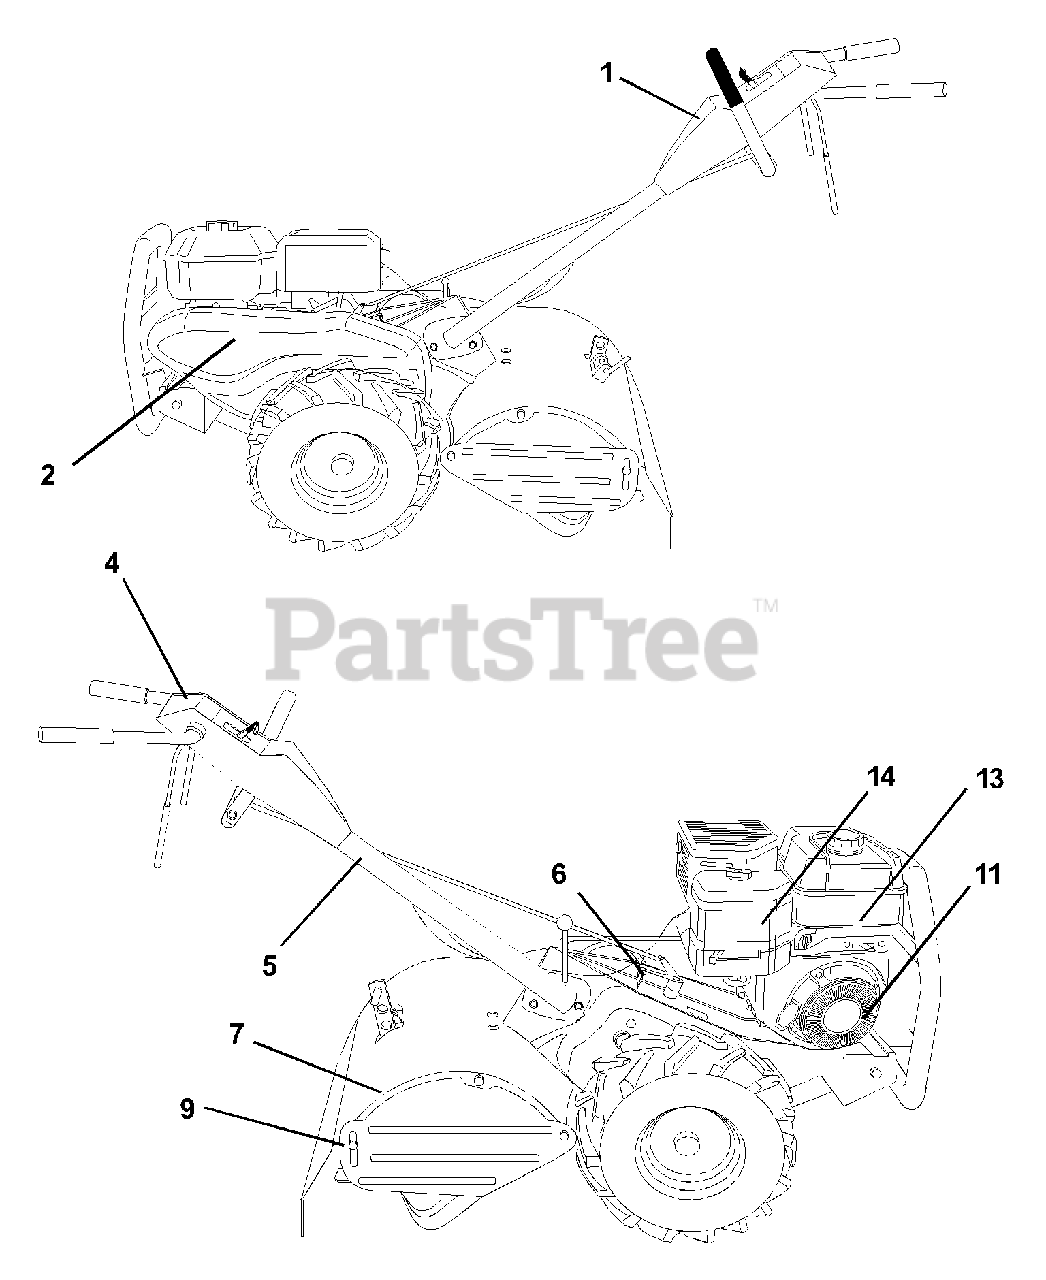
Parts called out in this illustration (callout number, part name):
1	Decal, Logo,Control Panel
2	Decal, Logo, Belt Guard
4	Decal, Instruction, Tilling
5	Decal, Hand Placement
6	Decal, Shift Indicator
7	Decal, Caution
9	Decal, Warning, Rotating Tines
11	Decal, B&S Rewind
13	Decal, B&S Tank
14	Decal, B&S Air Cleaner
